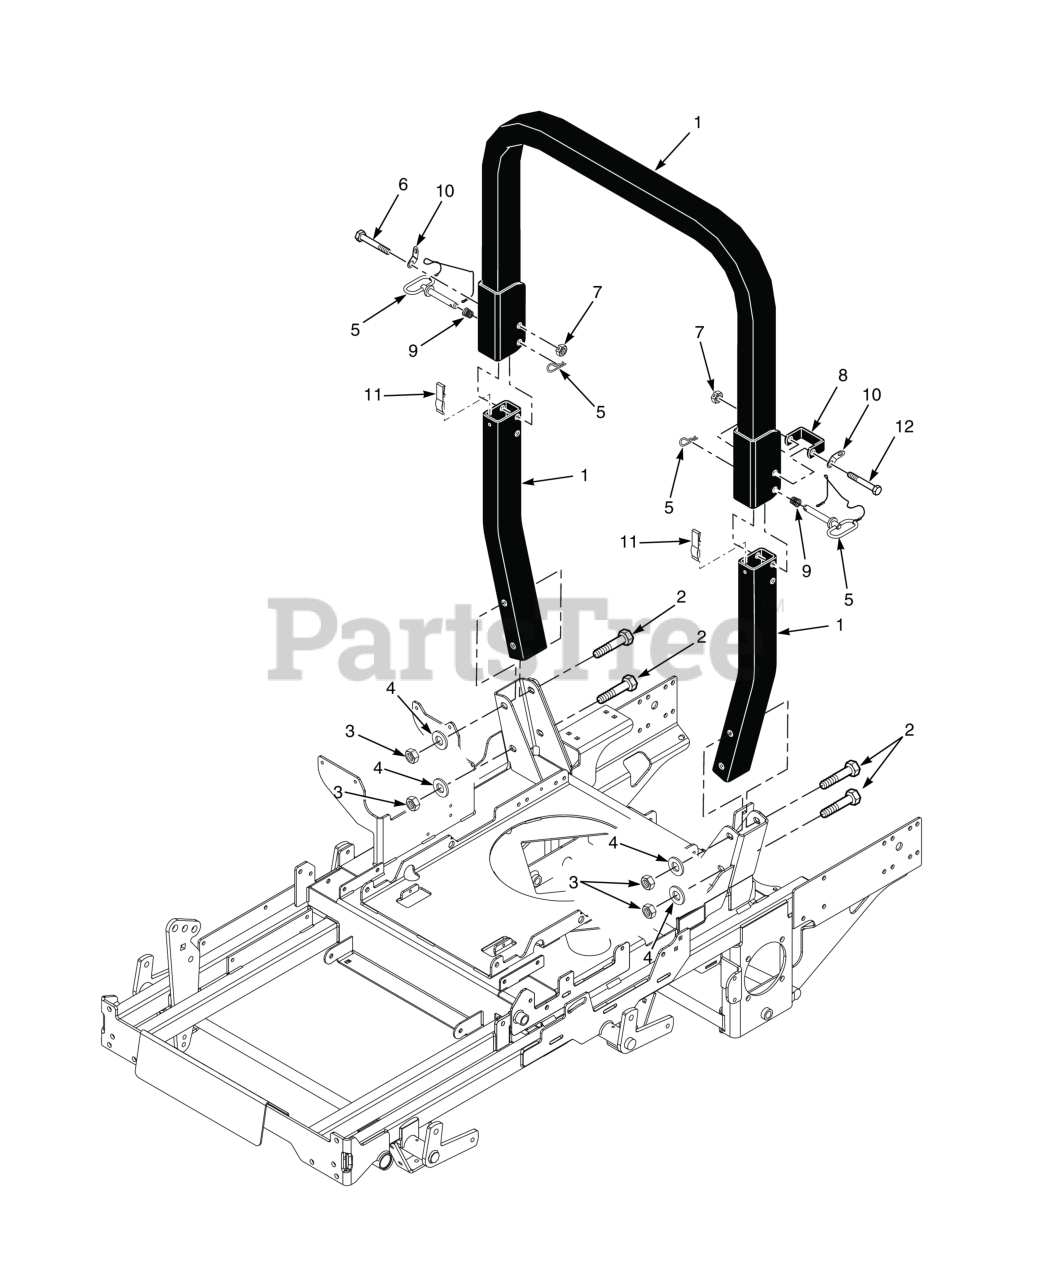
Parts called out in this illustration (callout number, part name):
1	STT, ROPS
2	Bolt, Hex Head 1/2-13 x 4-1/4"
3	Locknut, Hex 1/2-13 Center Lock
4	Flat Washer, 1/2 (.562 x 1.375 x .109)
5	Pin Assembly, ROPS Hinge
6	Bolt, Hex Head, 1/2-13 x 3-1/4"
7	HEX LOCKNUT, ELASTIC STOP, 1/2-13
8	Stop, ROPS
9	Spring, ROPS
10	Clip, ROPS
11	Spring, ROPS Anti-Rattle
12	Bolt, Hex Head 1/2-13 x 3-3/4"
